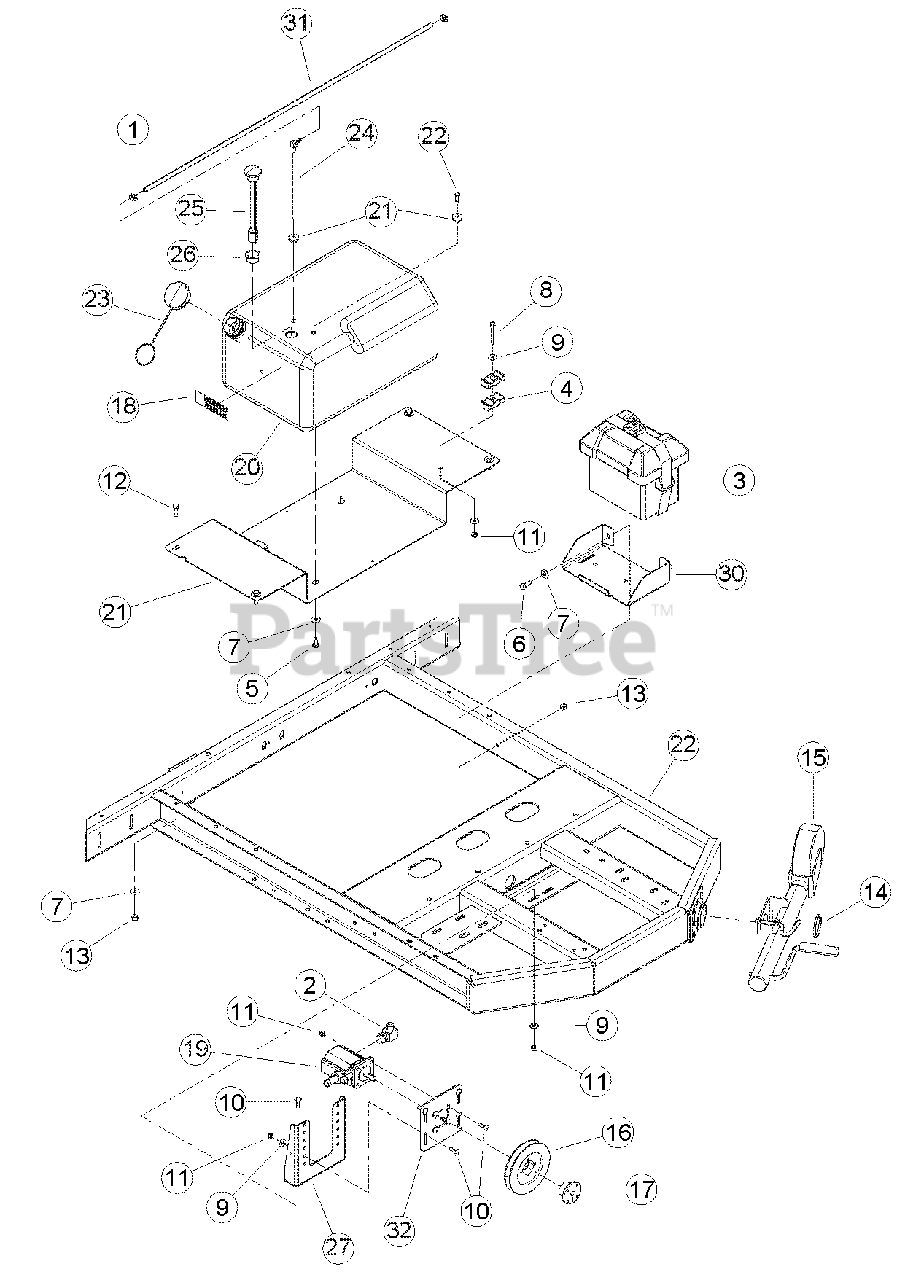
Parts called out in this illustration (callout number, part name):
1	CLAMP, HOSE 5/16 X 5/8 DIA. MAX
2	ADAPTER, -10 MORING / -8 MJIC 90 DEG.
3	BOLT, 3/8 X 3/4 HEX HD GR5 ZP
4	BOLT, 3/8 X 1 HEX HD GR5 ZP
5	WASHER, 3/8 FLAT ZP
6	WASHER, 5/16 FLAT ZP
7	BOLT, 5/16 X 1 CRG GR5 ZP
8	NUT, 5/16 NE NYLOCK ZP
9	BOLT, 3/8 X 1-1/4 CRG GR5 NC ZP
10	NUT, 3/8 NE NYLOCK ZP
11	JACK, PIVOTING W/SWIVEL CASTOR
12	SHEAVE, QT 1B5.6
13	BUSHING, QT 1/2
14	PUMP, CW HI/LO .605 DISP.
15	TANK, 9.5 FAL ROTOMOLDED FUEL
16	GROMMET, TANK FITTING
17	PLUG, TANK VENT
18	CAP, FUEL TANK VENTED
19	FITTING, TANK FUEL PICK-UP TUBE
20	GUAGE, FUEL TANK KELCH 100
21	GROMMET, KELCH 100 GUAGE
22	MOUNT, PUMP
23	HOSE, 63 IN. FUEL LINE
24	BASE, 9.5 GAL NYLON TANK
25	MOUNT, PUMP
26	WELDMENT, CHIPPER TRAILER
27	BRACKET, BATTERY HOLDER
